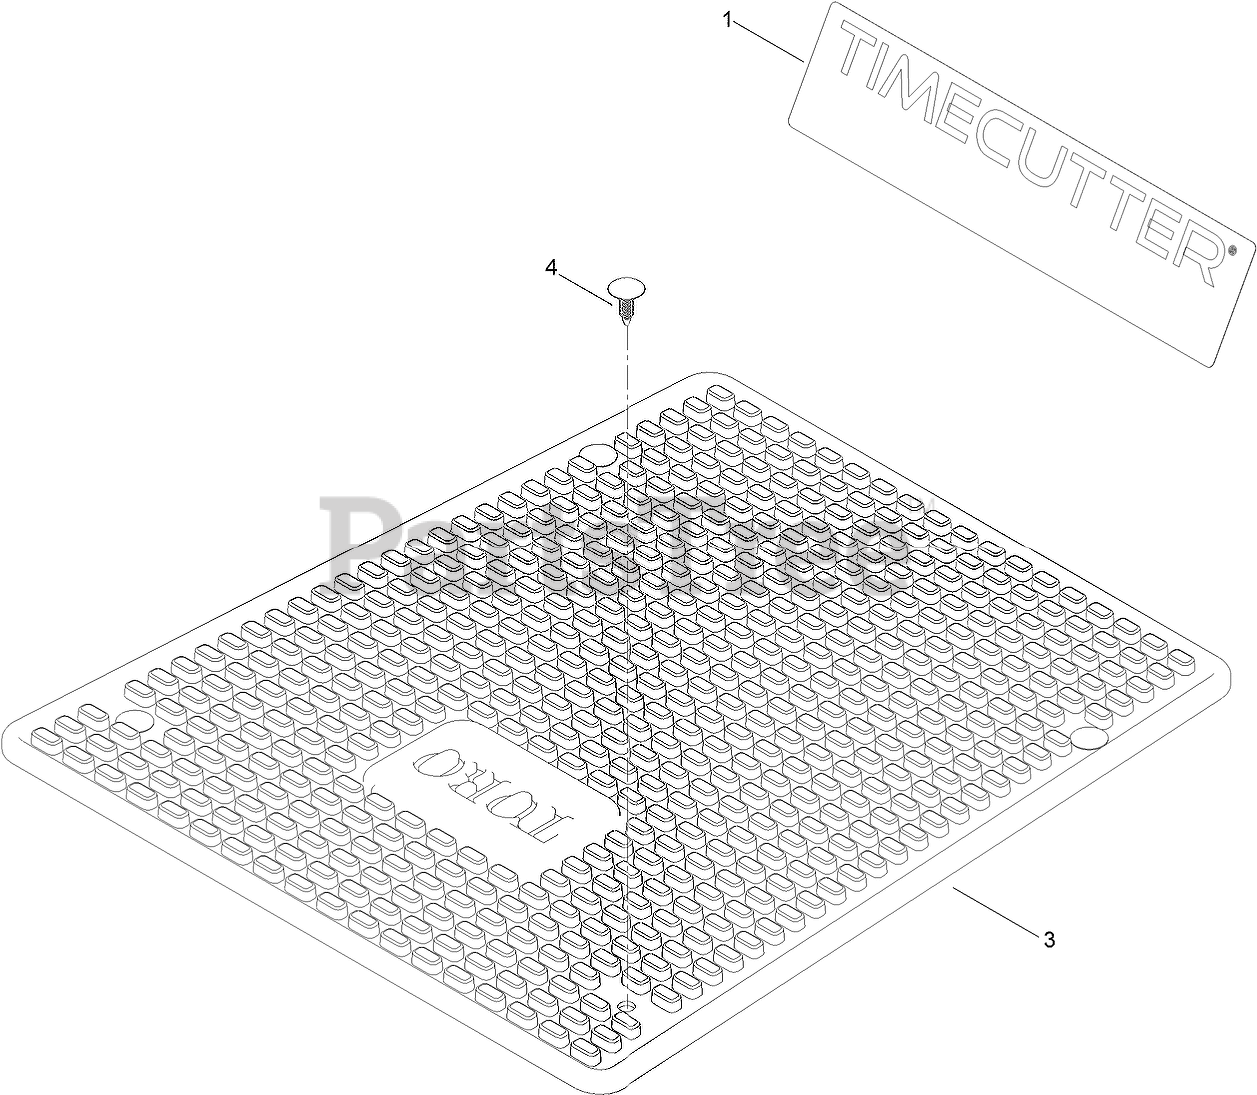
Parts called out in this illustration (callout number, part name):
1	DECAL-TIMECUTTER
3	MAT-FLOOR
4	PLUG-PLASTIC
